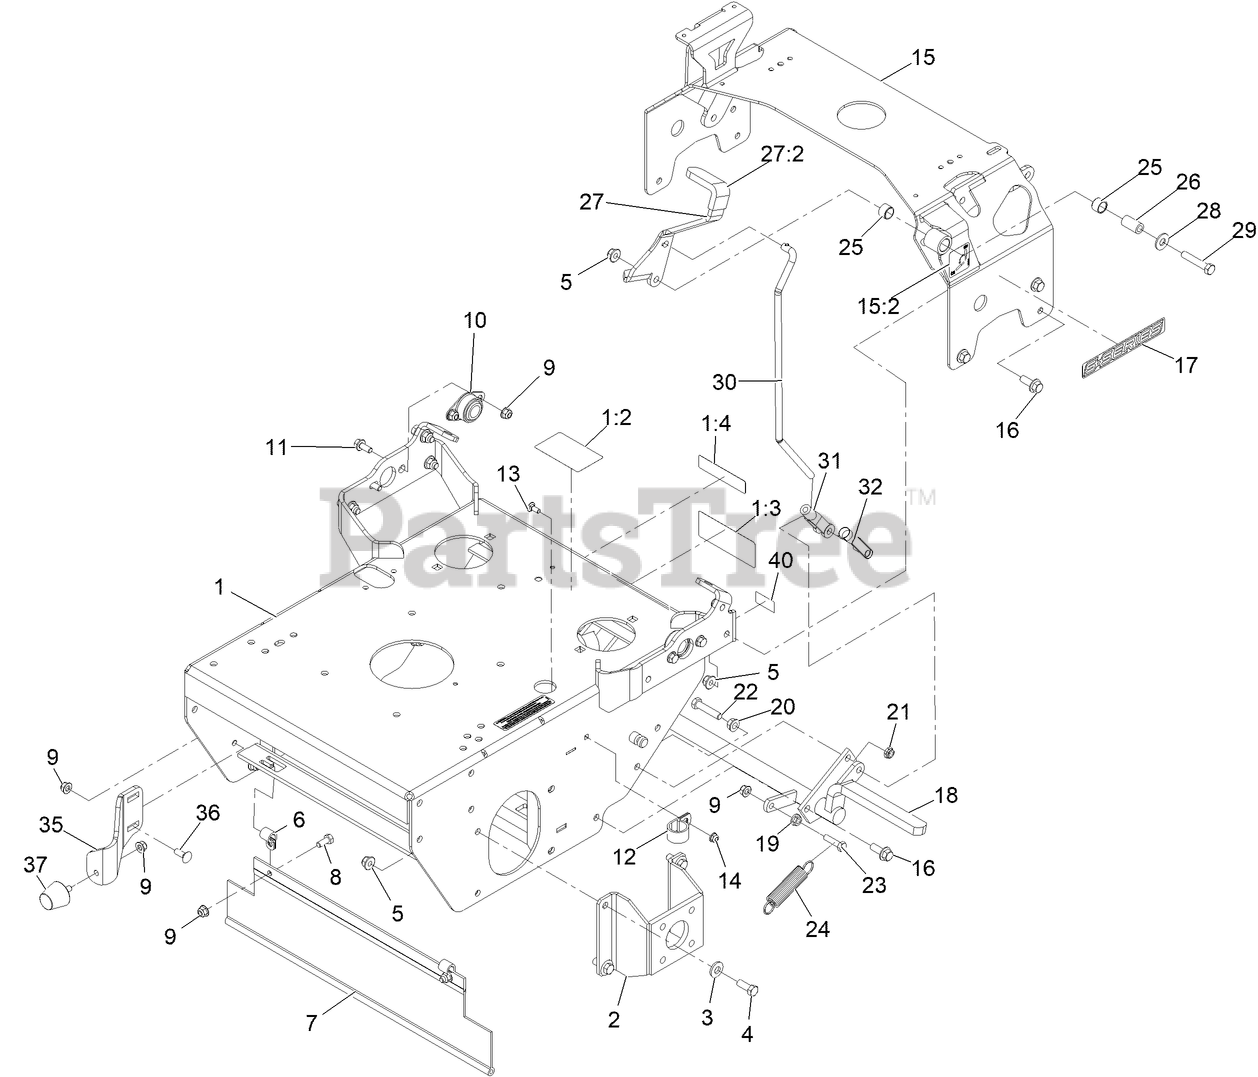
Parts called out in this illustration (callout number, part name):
1	ASM, ENGINE DECK W/ DECALS
1:2	DECAL-DRIVE RELEASE
1:3	DECAL-WARNING, SULKY
1:4	DECAL-WARNING
2	WLD,MOTOR MOUNT 36
3	WASHER-BELLEVILLE
4	SCREW-HH
5	NUT-HF, NI
6	CLIP-LOOM
7	SHIELD-DRAG
8	SCREW-HH
9	NUT-HF, NI
10	BEARING-FLANGE, SIDE
11	SCREW-HHF
12	CLIP-LOOM
13	SCREW-CARR
15	ASM-Tank Support
15:2	DECAL-PARK BRAKE, CE
16	SCREW-HHF 3/8-16 X 1
17	DECAL-S-SERIES
18	SHAFT-CROSS, BRAKE
20	NUT-HHF, WHIZ
22	SCREW-HH
23	SCREW-HH
24	SPRING-IDLER
25	SLEEVE-BUSHING
26	BUSHING-PIVOT
27	ASM, BRAKE LEVER W/ GRIP
27:2	GRIP-LEVER
28	WASHER-FLAT
29	SCREW-HH
30	LINKAGE, BRAKE
31	YOKE-LINKAGE, BRAKE
32	PIN-SPRING, CLEVIS
35	BRACKET-BUMPER
36	SCREW-CARR
37	BUMPER-RUBBER
40	Decal-Patent Ttco.Com
